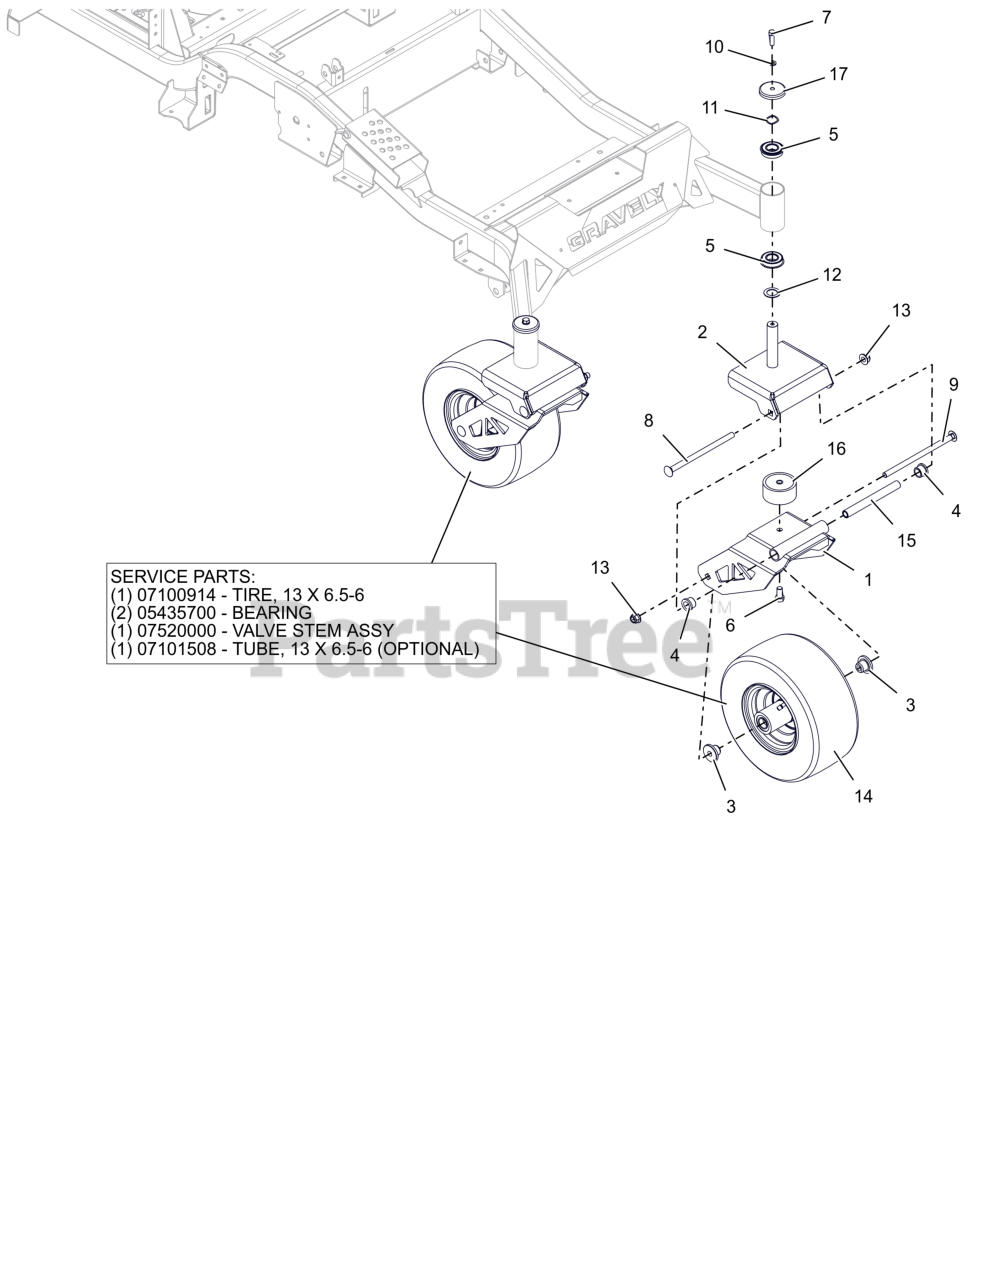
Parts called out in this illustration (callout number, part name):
1	WLDMT, LOWER SUSPENSION (RED)
2	WLDMT- UPPER SUSPENSION FORK
3	SPACER, FRONT WHEEL
4	BUSHING, FLANGE .75X.75X1.0
5	BEARING, BALL -2.000 OD X 1.000 ID X .5625 W/RING
6	BLT, HEX .50-13X1.00 G5 ZCC
7	BLT- HEX .38-16X1.25 G5 ZB500
8	BLT, RHSN .50-13X8.50 G5 ZCC
9	BLT-RHSN .50-13X9.00 G5 ZCC NS
10	WSHR-LK-REG .375X.094 ZB500
11	WSHR-WAVE 1.0X1.25X.028 .145FH
12	WSHR-HRD-THRS 1.007X1.542X.062
13	NUT,NYL-FLG .50-13 GF ZCC
14	ASM-TIRE/WHEEL 13X6.50-6
14	TIRE, 13X6.50-6 SMOOTH
14	BRG, 25MM ID X 52MM OD X 15MM
14	VALVE STEM ASS'Y
14	TIRE TUBE 13X6.5-6
15	ROD, FORK PIVOT
16	SPCR, RUBBER SUSPENSION
17	SHIELD- AXLE BEARING
